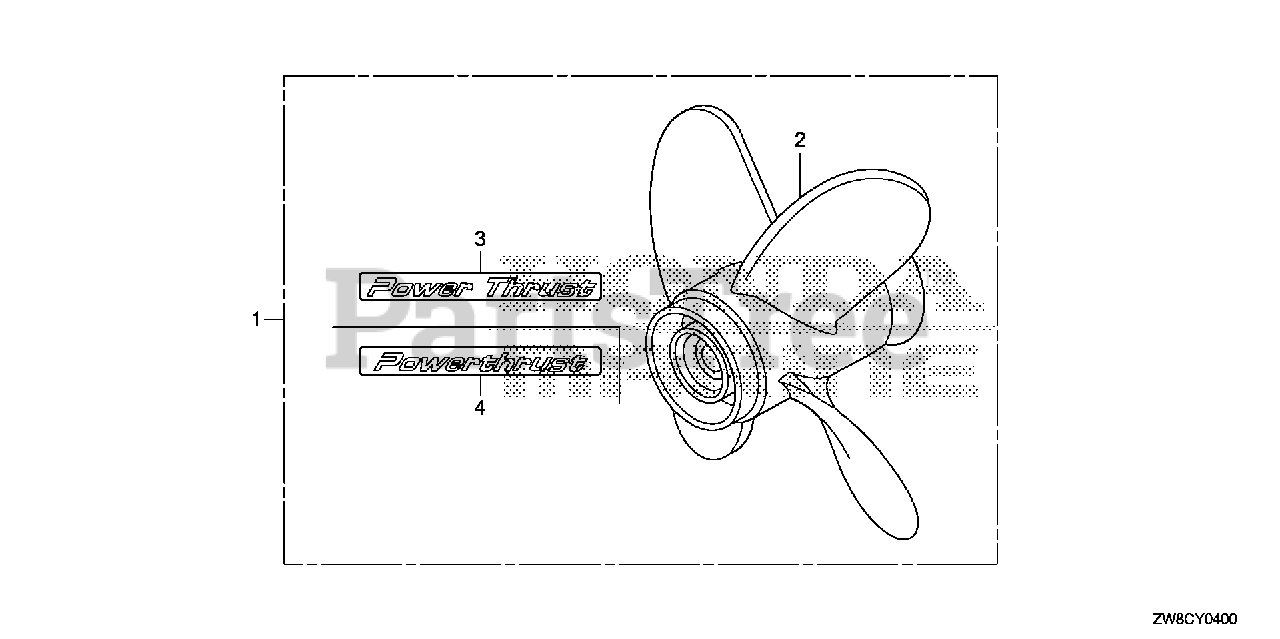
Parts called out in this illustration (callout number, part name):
1	PROPELLER KIT, POWER THRUST *NH283* (STIN GRAY)
2	PROPELLER, FOUR BLADES (10X6-1/2 HT) *NH283* (STIN GRAY)
3	MARK, POWER THRUST
